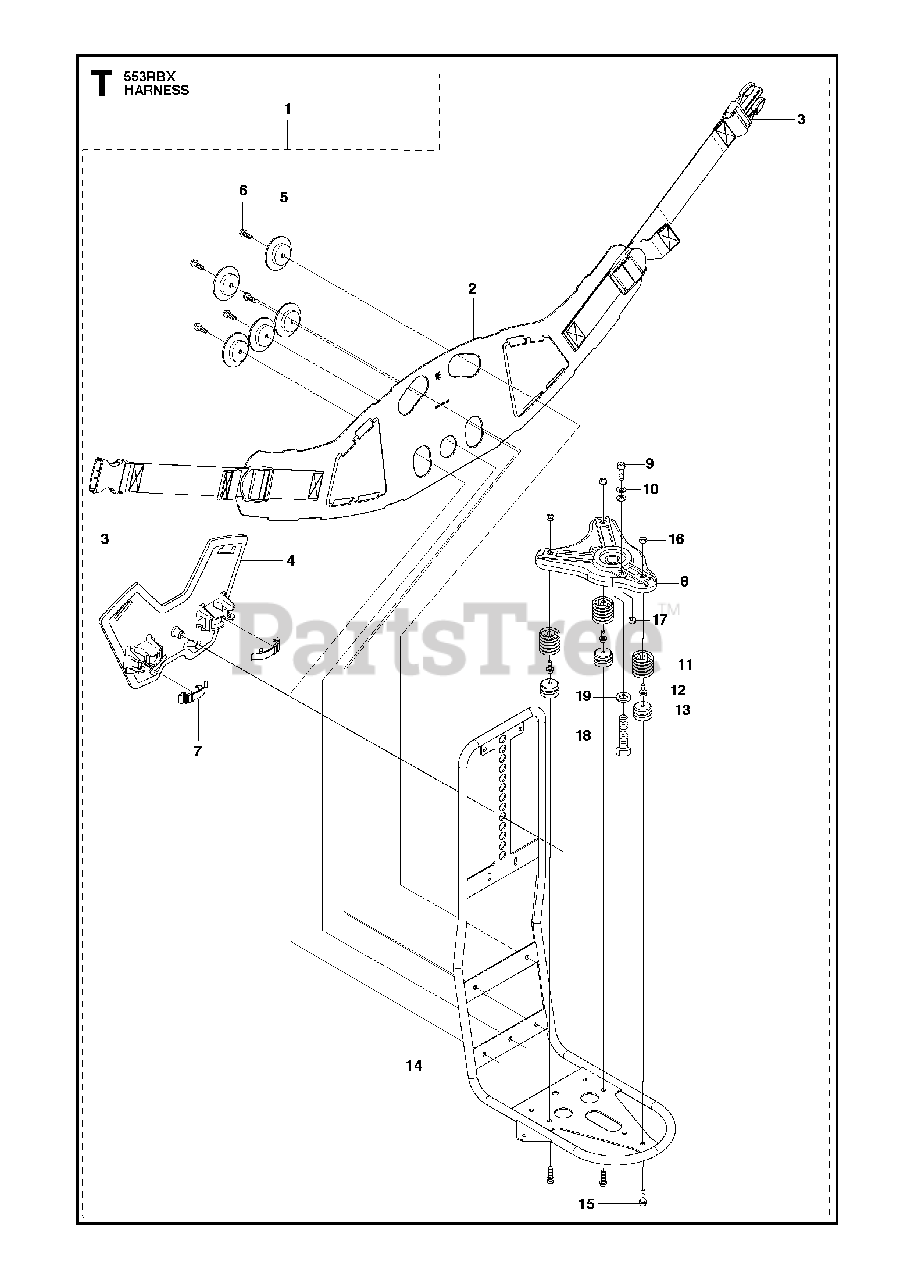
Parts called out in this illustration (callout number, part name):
3	BUCKLE
6	Screw, Ihscft
7	HOLDER
9	SCREW IHSCM
10	NUT
12	SCREW
15	SCREW
16	NUT
17	NUT
18	Screw, M10 X 25
19	WASHER
